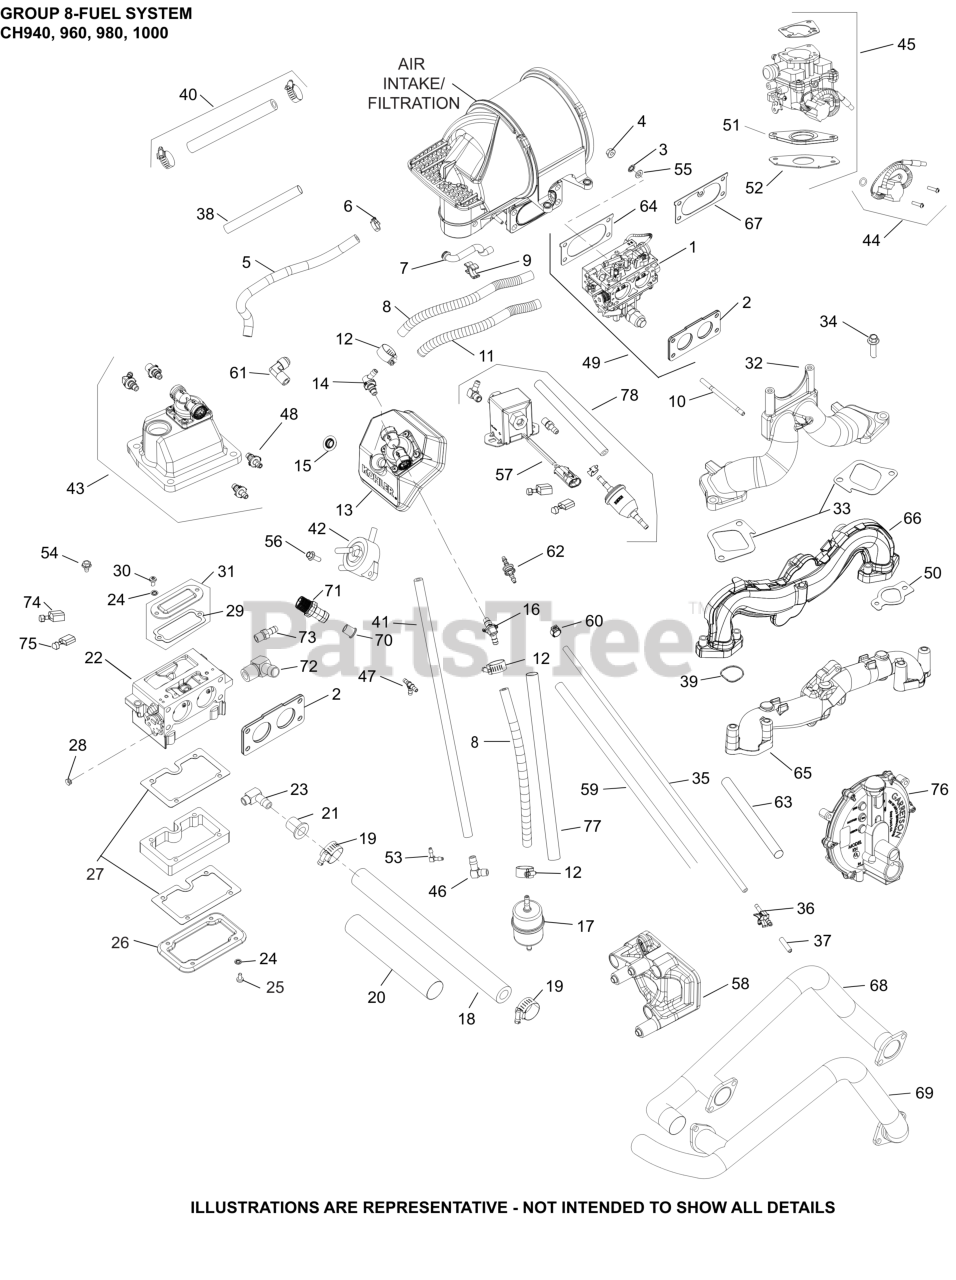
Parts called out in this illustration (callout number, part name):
2	GASKET, CARBURETOR
3	WASHER, INT TOOTH LOCK 1/4"
4	NUT, FLG M6X1.0
5	HOSE, FUEL LOW PERMEATION
8	HOSE,LW PERM.FUEL 24.00"-USE 25 111 81-S
10	STUD-USE 25 072 47-S
12	CLAMP, HOSE (KM)-USE 25 237 31-S
13	KIT, FUEL PUMP
14	KIT, 90 DEG. FITTING
16	KIT, 45 DEG. FITTING
17	FILTER, FUEL
32	KIT, INTAKE MANIFOLD
33	GASKET, INTAKE MANIFOLD
46	CONNECTOR, HOSE
49	KIT, CARBURETOR COMPLETE
NI	KIT, SOLENOID VALVE REPAIR
NI	KIT, OVERHAUL
NI	KIT, FLOAT REPAIR-DISCONTINUED
NI	KIT, HIGH ALT (4000-8000 FT))
NI	KIT, HIGH ALT (8,000+ FT)
NI	KIT, CHOKE
